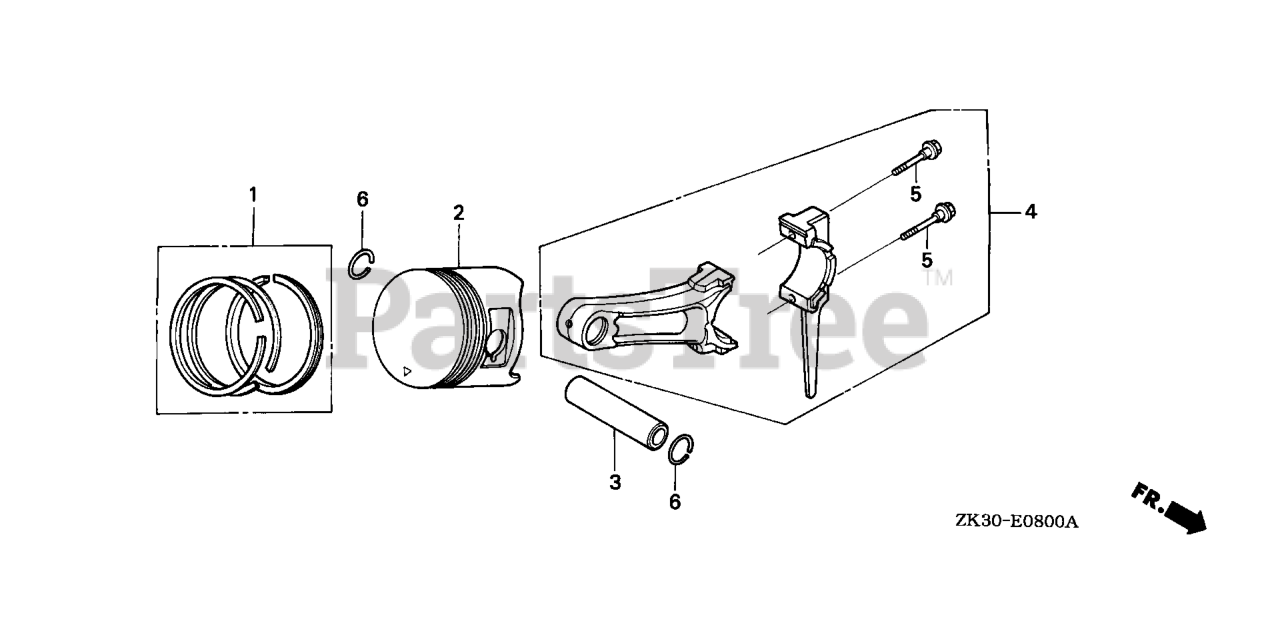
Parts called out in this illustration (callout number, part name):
1	RING SET, PISTON (STD)
1	RING SET, PISTON (OS 0.25)
1	RING SET, PISTON (OS 0.50)
1	RING SET, PISTON (0.75)
1	RING SET, PISTON (0.75) (TEIKOKU)
2	PISTON (STD)
2	PISTON (OS 0.25)
2	PISTON (OS 0.50)
2	PISTON (OS 0.75)
3	PIN, PISTON
4	ROD ASSY., CONNECTING (US 0.25)
4	ROD ASSY., CONNECTING (STD)
5	BOLT, CONNECTING ROD
6	CLIP, PISTON PIN (20MM)
